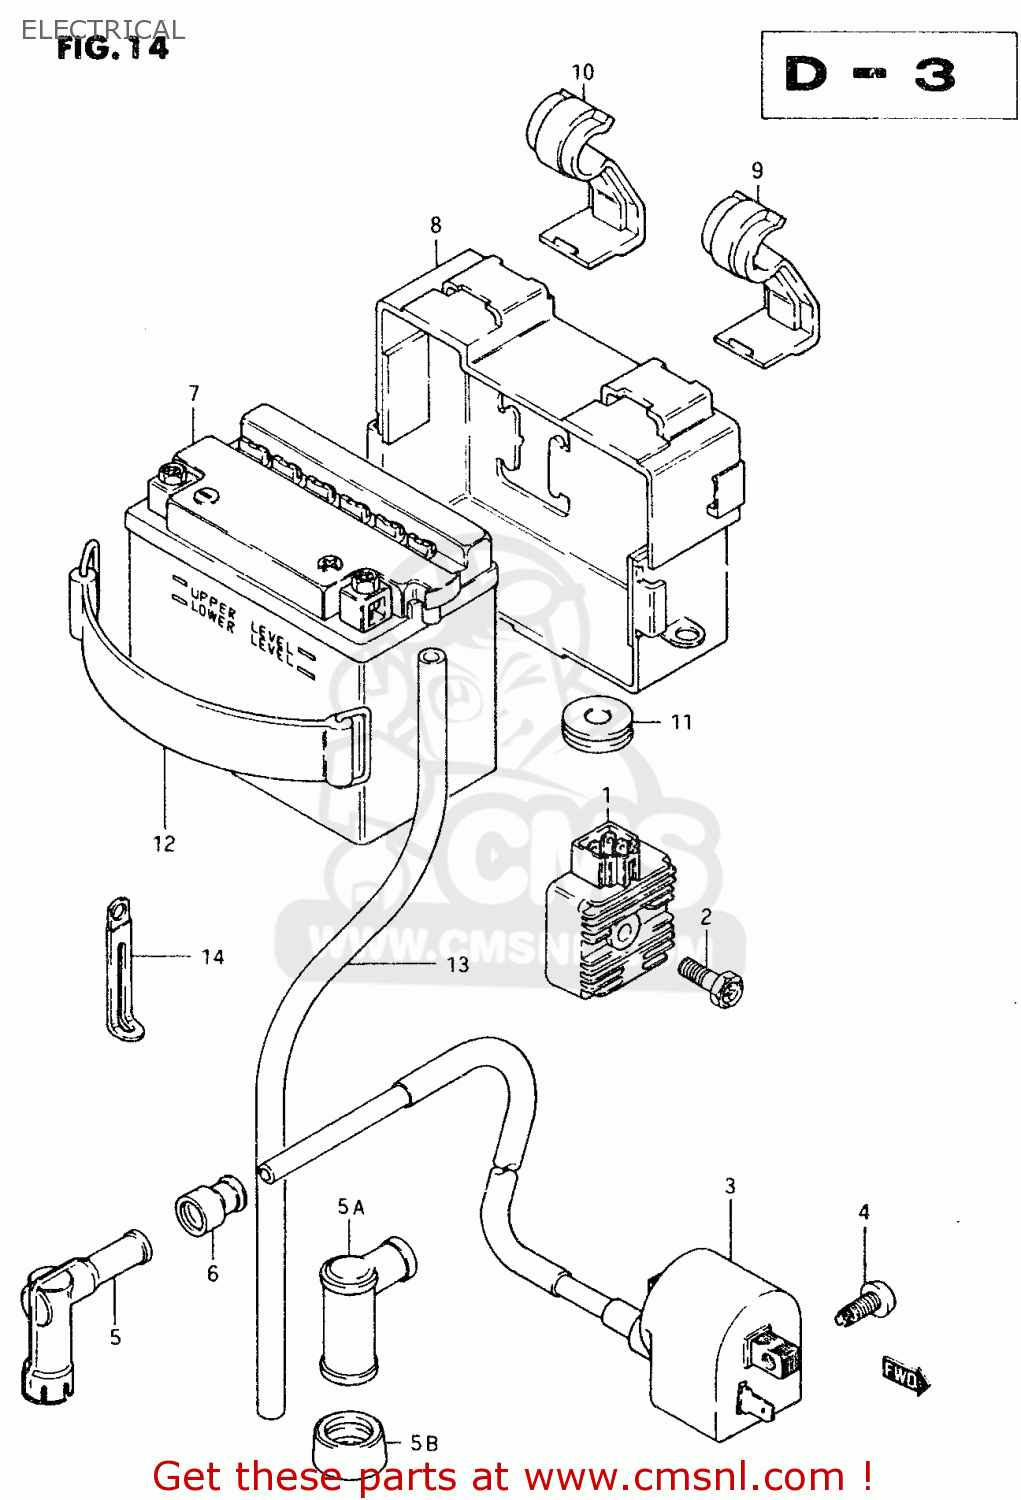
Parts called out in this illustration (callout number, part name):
1	RECTIFIER ASSY,REGULATOR
2	SCREW (6X25)
3	UNIT & COIL ASSY,IGNITION
4	SCREW 6X16
5	CAP,SPARK PLUG
5A	CAP ASSY,SPARK PLUG
5B	SEAL,SPARK PLUG
6	SEAL,HIGH TENSION CORD
7	BATTERY ASSY(YB4L-B,12V4.2AH)
8	HOLDER,BATTERY
9	HOOK,BATTERY HOLDER FR
10	HOOK,BATTERY HOLDER RR
11	CUSHION
12	BAND
13	HOSE,BATTERY EXHAUST
14	CLAMP
